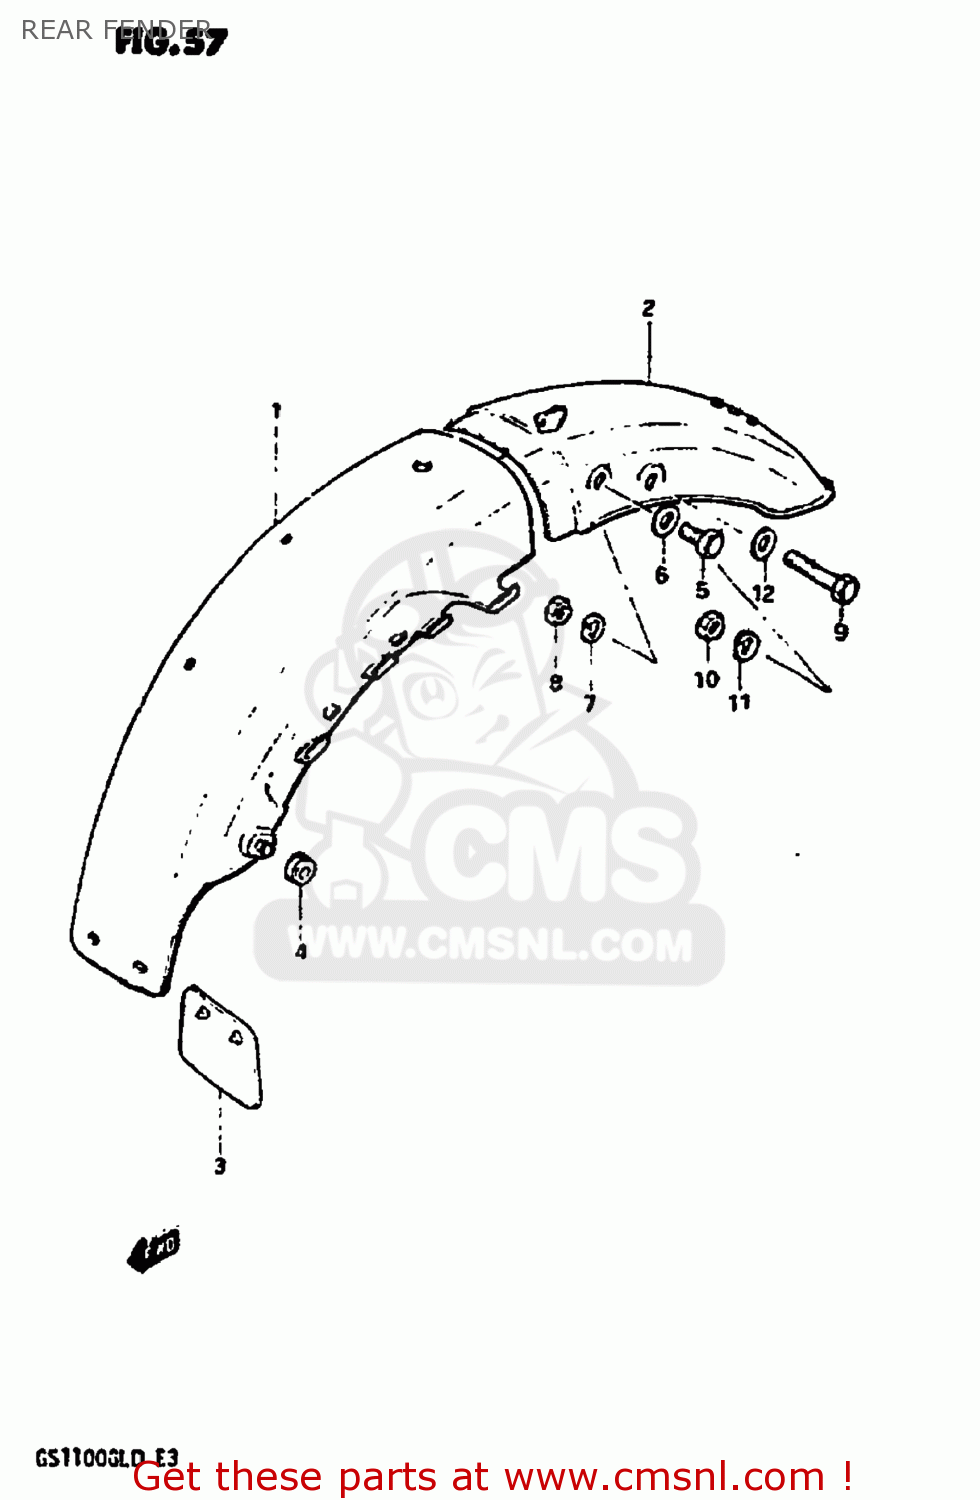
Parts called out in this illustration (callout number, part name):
1	FENDER,REAR
2	FENDER,REAR
3	GUIDE,RR FENDER MUD
4	CUSHION
5	BOLT
6	WASHER
7	LOCK WASHER
8	NUT 8MM
9	BOLT
10	NUT 8MM
11	LOCK WASHER
12	WASHER
